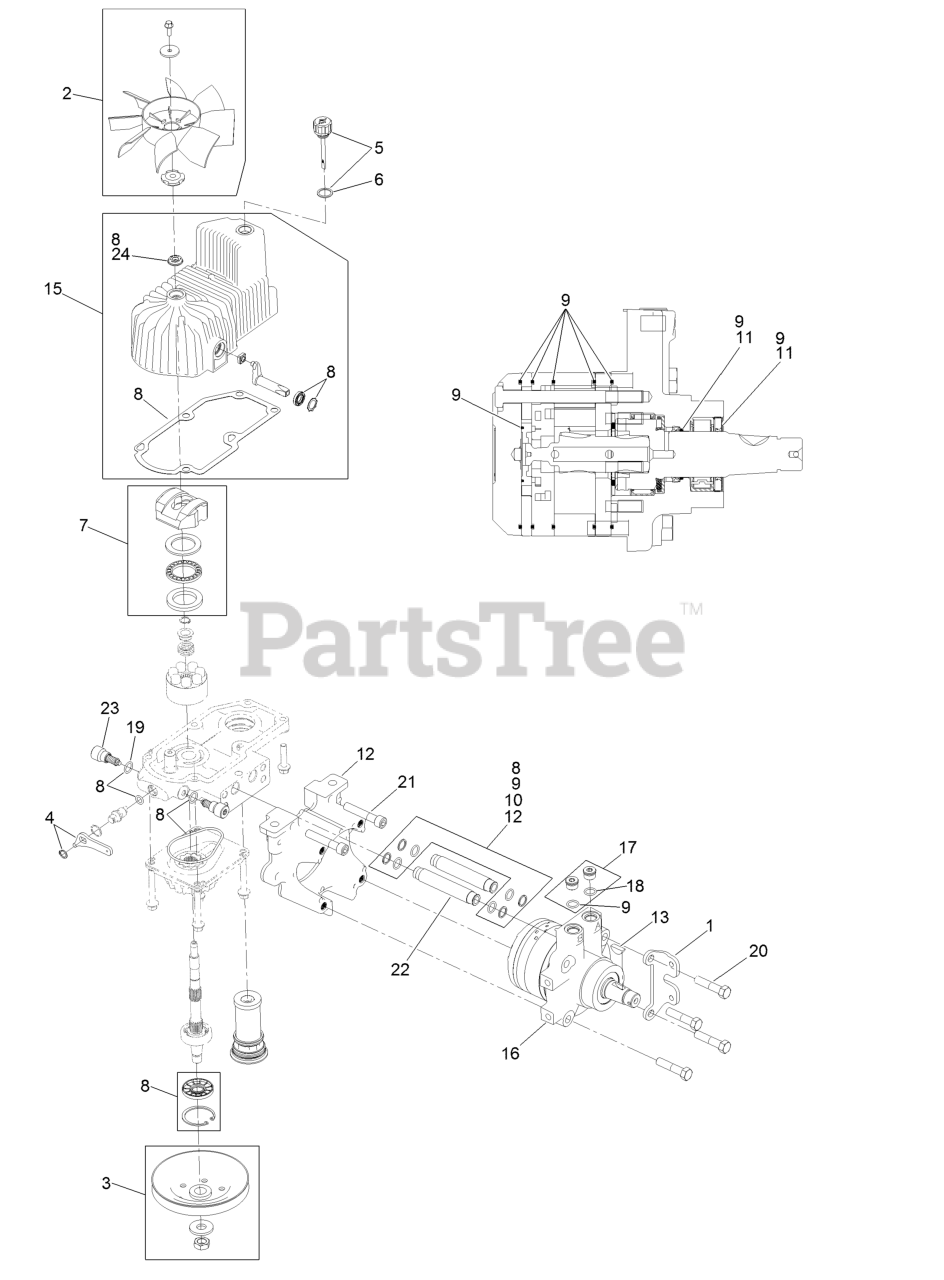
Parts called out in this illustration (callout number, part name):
1	Mount-Shoe, Horse
2	Fan Kit
3	Pulley Kit
4	Handle-Bypass Valve, Hydro
5	Dipstick-Hydro W/Gasket
6	Gasket-Dipstick, Hydro
7	Swash Block Kit
8	Pump Seal Kit
9	Motor Seal Kit
10	Tube Seal Kit
11	Output Shaft Seal Kit
12	Nose Cup-Uht
13	Key-Woodruff
15	Housing-RH
16	Motor-Hydraulic RH 240Cc
17	Magnetic Plugs Service Kit
19	O-Ring-Check Valve
20	Screw HH
21	Screw-HSH
22	Hydraulic Tube Kit
23	Shock Valve, 12Cc Hydro
24	Seal-Fan Drive
99	Puller-Pulley
99	Flow Test Kit
